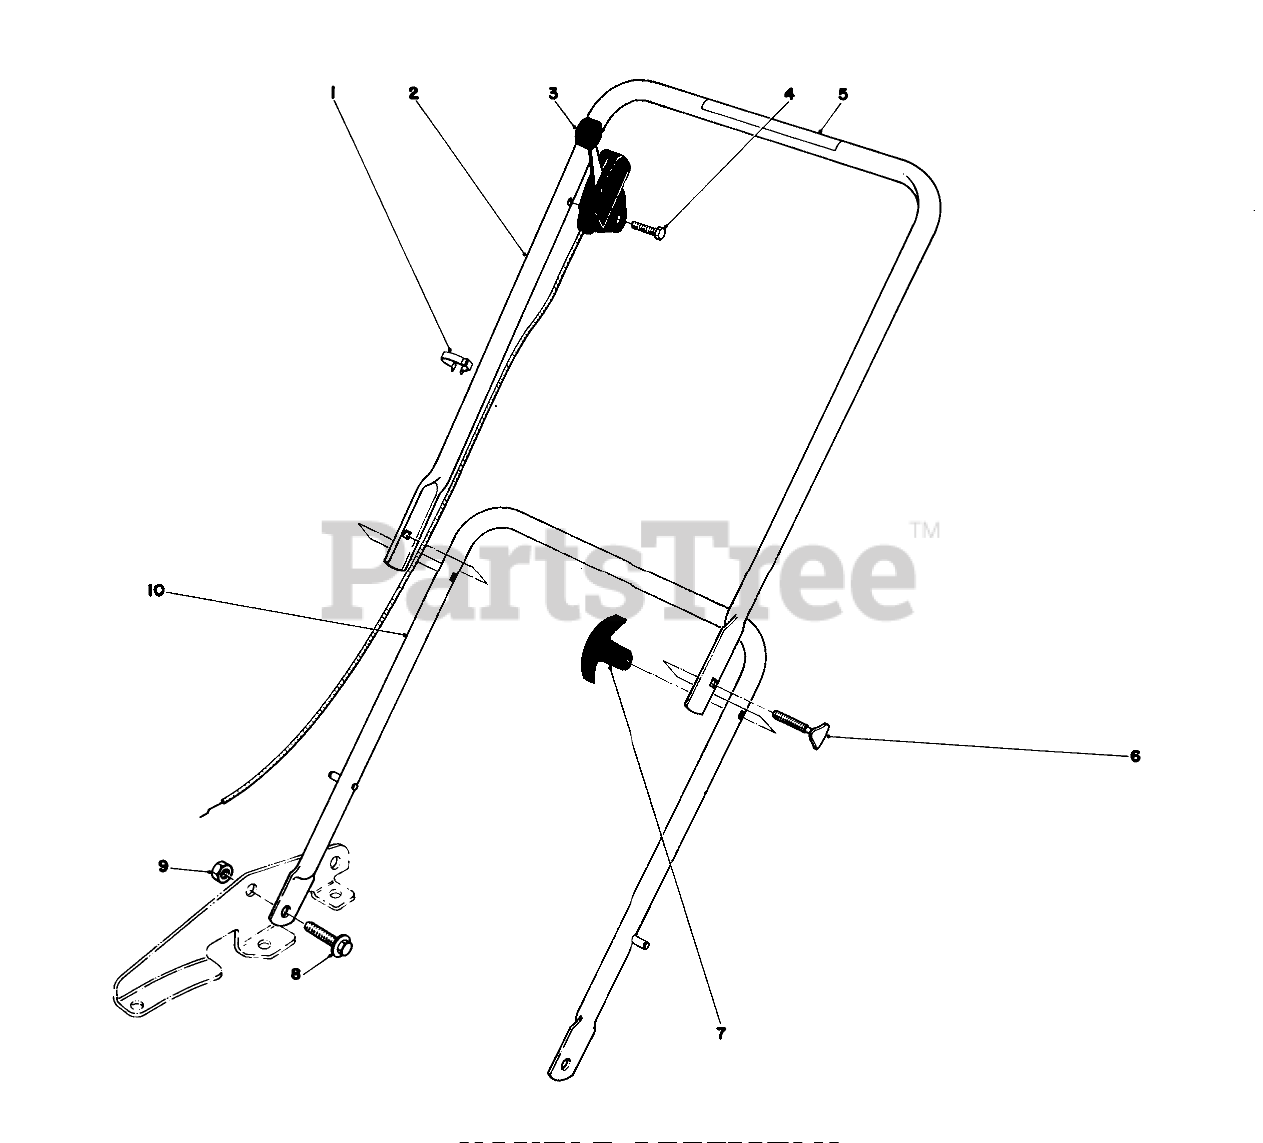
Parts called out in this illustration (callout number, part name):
1	BOWDEN CLIP
2	UPPER HANDLE
3	Throttle Control
5	Decal-Danger
6	HANDLE SCREW
8	SCREW-SHOULDER
9	NUT-LOCK, CONE
10	Lower Handle
